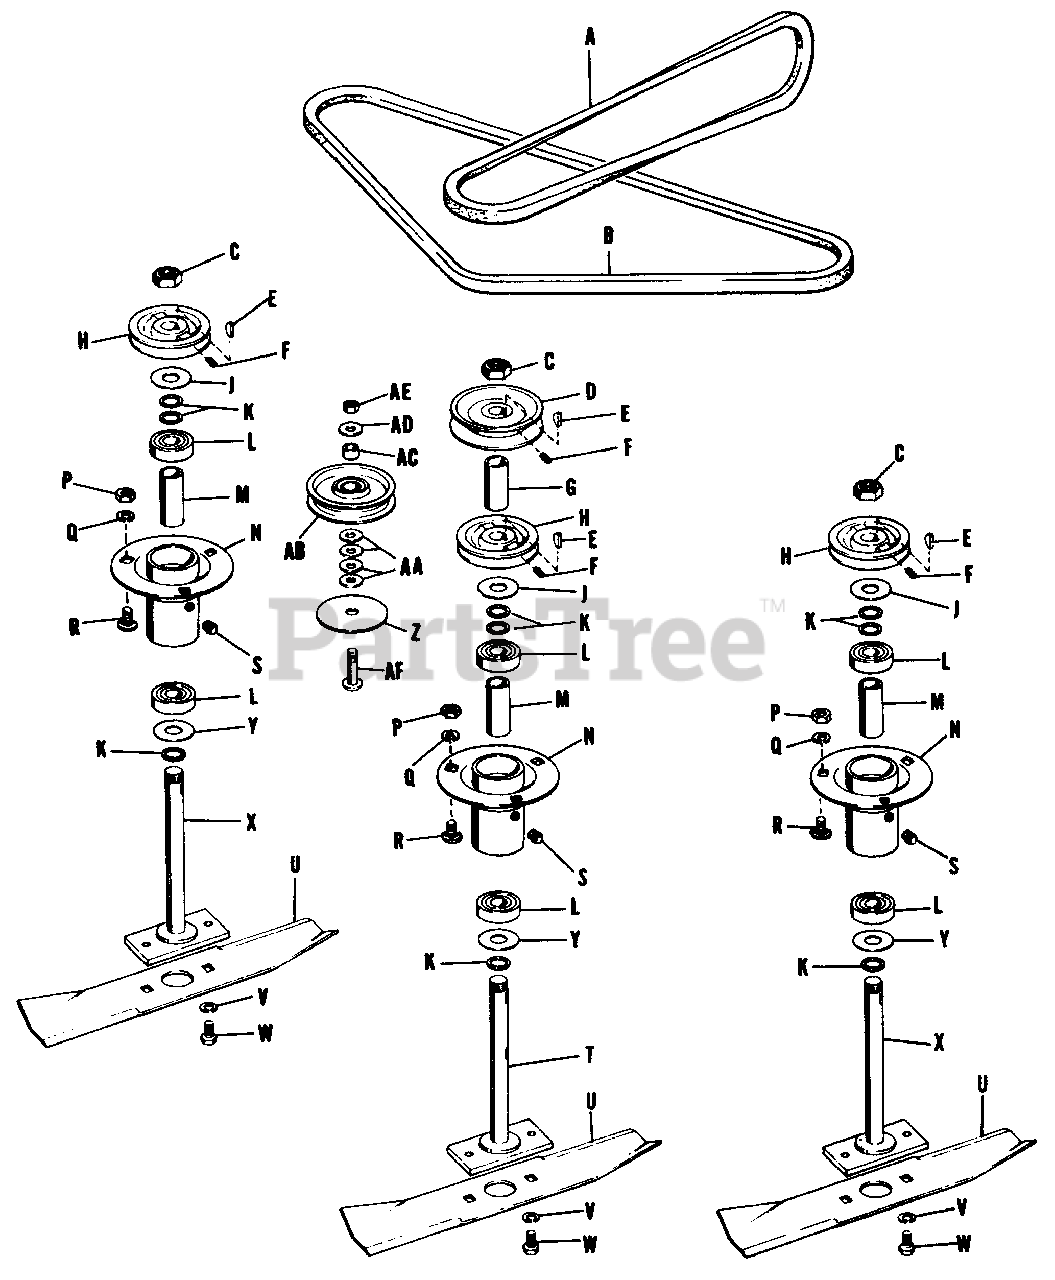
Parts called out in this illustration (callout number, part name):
A	Belt, "V " (Cross Drive)
B	Belt, "V" (Mower Spindle Drive)
C	Nut, Jam, Hex, Lock, 3/4"-16 NF
D	Pulley, Cross Drive
E	Key Woodruff, #61
F	Screw, Set, Cup Point Socket Hd., 5/16"-18 NC x 3/8" lg.
N	Tube Assembly, Arbor
P	Nut, Hex, Full, 3/8"-16 NC
Q	Washer, Lock, 3/8"
R	Bolt, Carriage, 3/8"-16 NC x 3/4"
S	Plug, Pipe, 1/8" Sq. Hd.
T	Arbor Assembly, Drive
U	Blade, Knife
V	Washer, Lock, 3/8"
W	Capscrew, Hex Hd., 3/8"-16 NC x 5/8" lg.
X	Arbor Assembly
AA	Washer, Plain, 5/16"
AB	Pulley, Idler
AD	Washer, Plain, 5/16"
AE	Nut, Hex, Full, Lock, 3/8"-16 NC
AF	Bolt, Carriage, 3/8"-16 NC x 1-1/2" lg.
